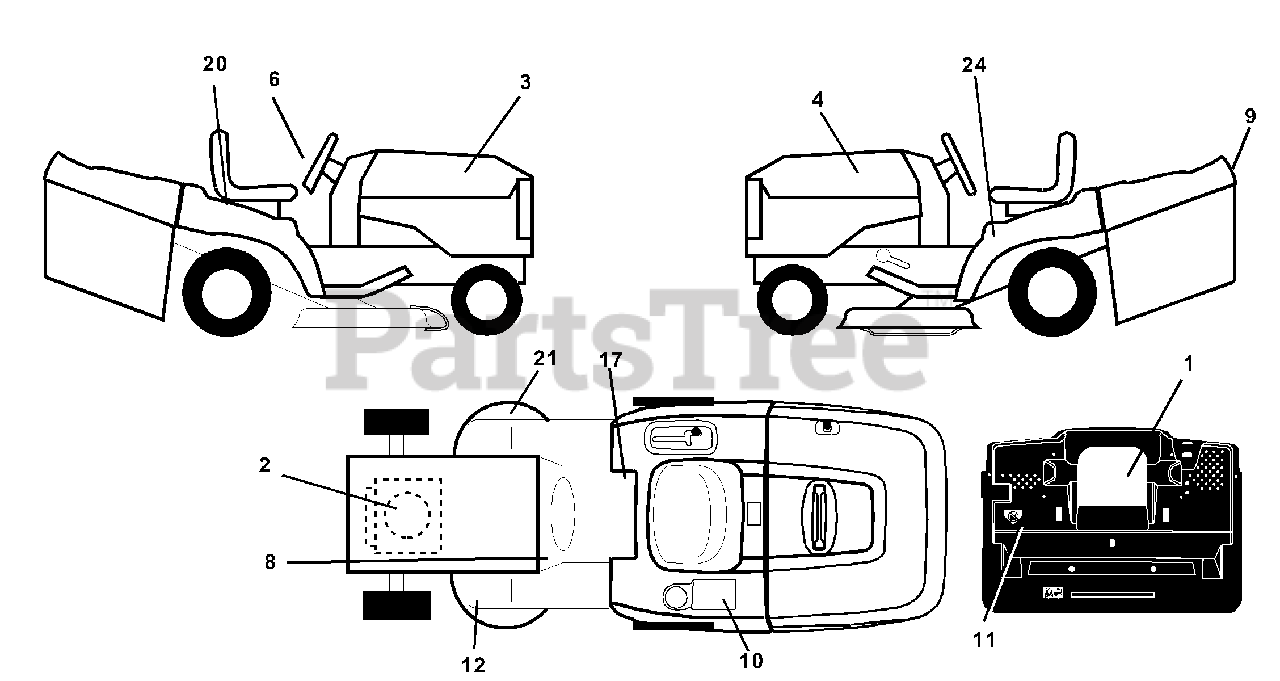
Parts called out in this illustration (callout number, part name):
1	Decal Mower Warn Keep Hand Away
2	Decal Hp Engine
3	Decal Hood Rh
4	Decal Hood Lh
6	Decal Steering Wheel
8	Decal Dash
9	Decal Fender
10	Decal Bat Dan/Poi P/L
11	Decal Mower Cut Finger
12	Decal Brake/Clutch E/Fr
17	Decal Saddle Oper Inst Hydro E/F
20	Decal Bypass Fender CRD
21	Decal Deck Sch 92 CRD
23	Decal Bagger/Discharge CRD
24	Decal Fender Danger E/F Lt
